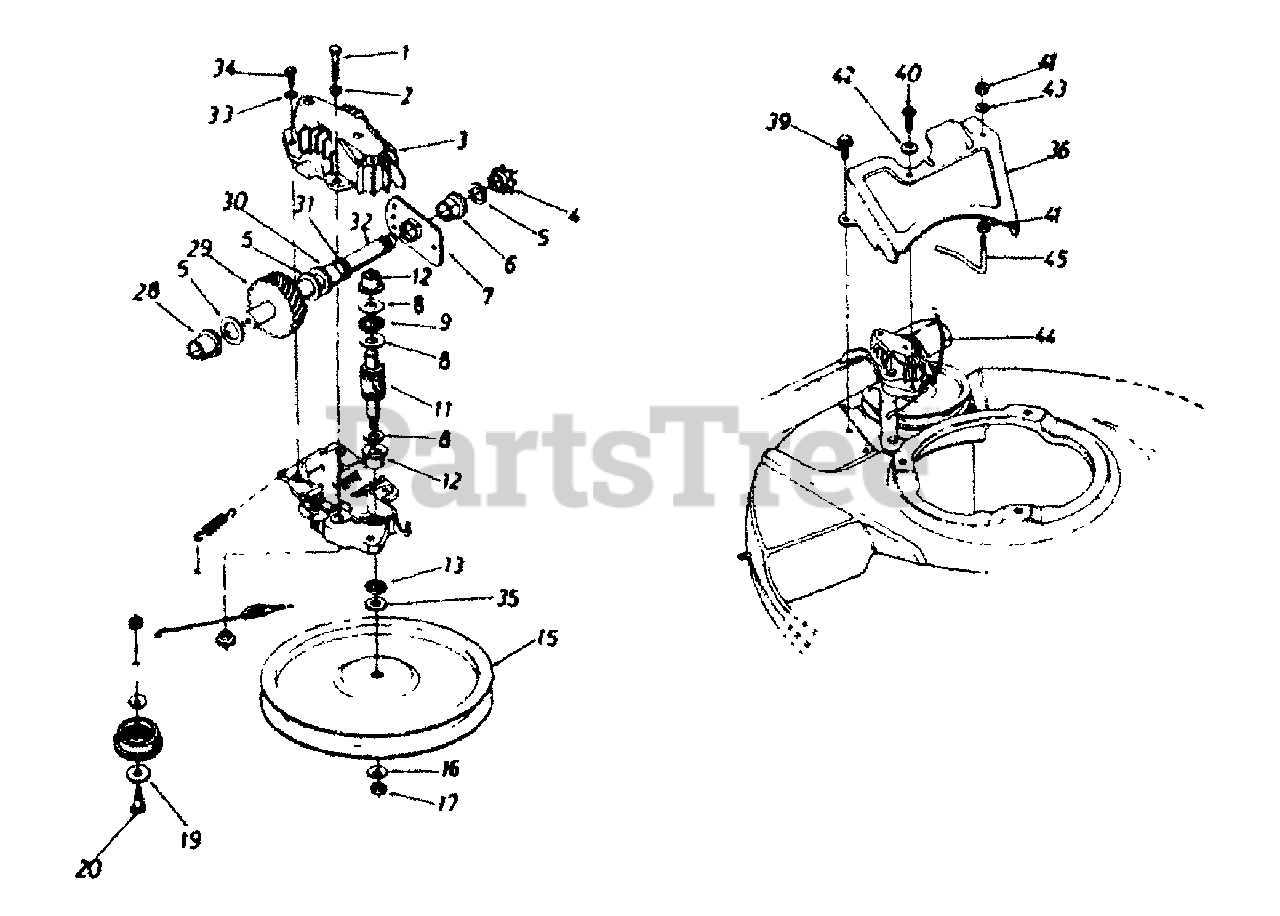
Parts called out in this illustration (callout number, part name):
1	Hex Bolt w/Patch 1/4-20 x 1.25"
2	L-Washer 1/4" ID
3	Upper Housing Half
4	#46 Sprocket 7 Tooth x 1/2 Pitch
5	Flat Washer 5/8" ID x .030 OD
6	Hex Flange Bearing .631" ID
8	Thrust Washer .362" ID x .70" OD
9	Thrust Bearing .375" ID x .812" OD
11	11 Tooth Helical Gear
12	Flange Bearing
13	Oil Seal
15	Pulley 5.06" ID
16	Bell Washer .265" ID x .75" OD
17	Hex Nut 1/4-28 LH Thread
19	Flat Washer .390" ID x 1.0" OD
20	Shoulder Bolt .375" x .40"
28	Flange Bearing .56"
29	33 Tooth Helical Gear
30	Flange Bearing .629"
31	Oil Seal .625"
32	Gear Sprocket Shaft
33	Lock Washer #10
34	Hex Tap Screw #10 x .62"
35	Hex Washer .26" x .88"
40	Hex Tap Screw 1/4 x .62"
41	Hex Nut 1/4-20
42	Bell Washer .265" ID x .75"
43	Lock Washer 1/4" ID
44	SP Cable - 48"
45	SP Belt Guard
